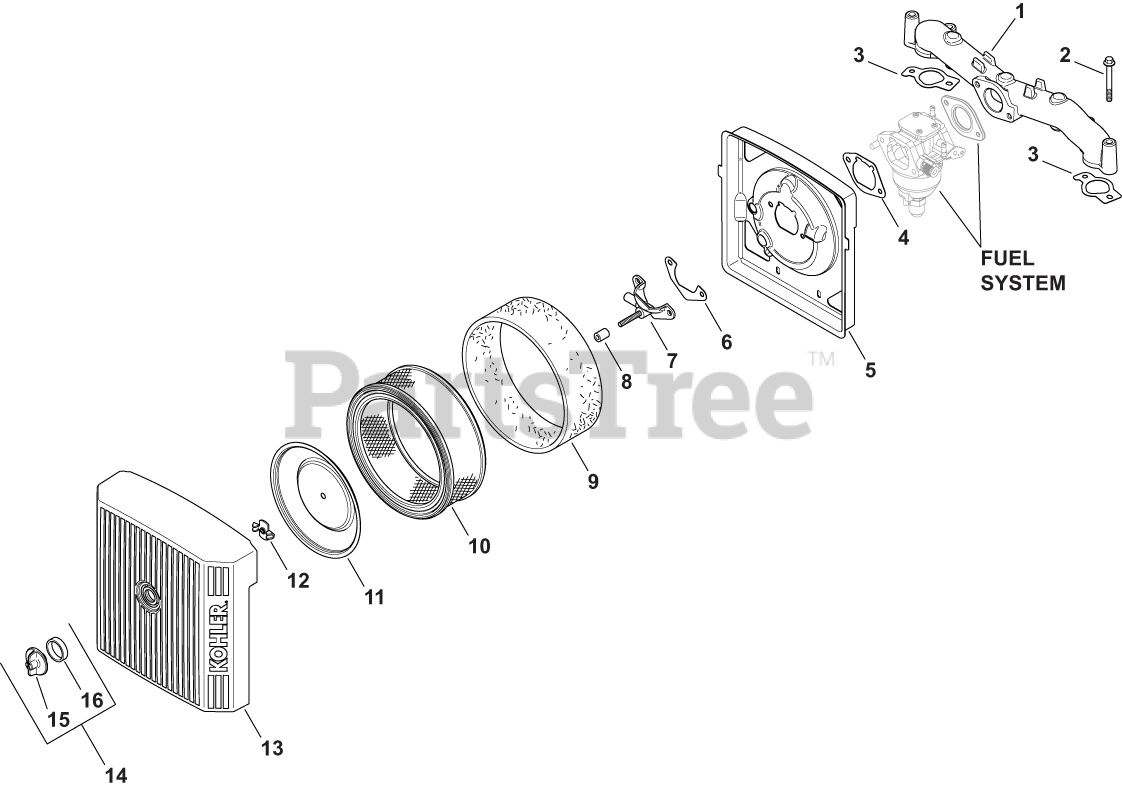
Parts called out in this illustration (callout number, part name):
1	MANIFOLD, INTAKE
2	SCREW, FLG M6X1.0X55
3	GASKET, INTAKE MANIFOLD USE 24 041 79-S
4	GASKET, AIR CLEANER BASE
5	BASE, AIR CLEANER
6	GASKET, FUEL SPITBACK CUP
7	CUP, FUEL SPITBACK W/NIPPLE
8	SEAL, BREATHER
9	PRE-CLEANER (HIGH)
10	ELEMENT, AIR FILTER (HIGH) - Also available Retail Packaged 24 883 03-S1 Air Filter Kit
11	COVER, INNER AIR CLEANER
12	NUT, WING
13	COVER, AIR CLEANER
14	KIT, KNOB W/SEAL
15	KNOB, COVER
